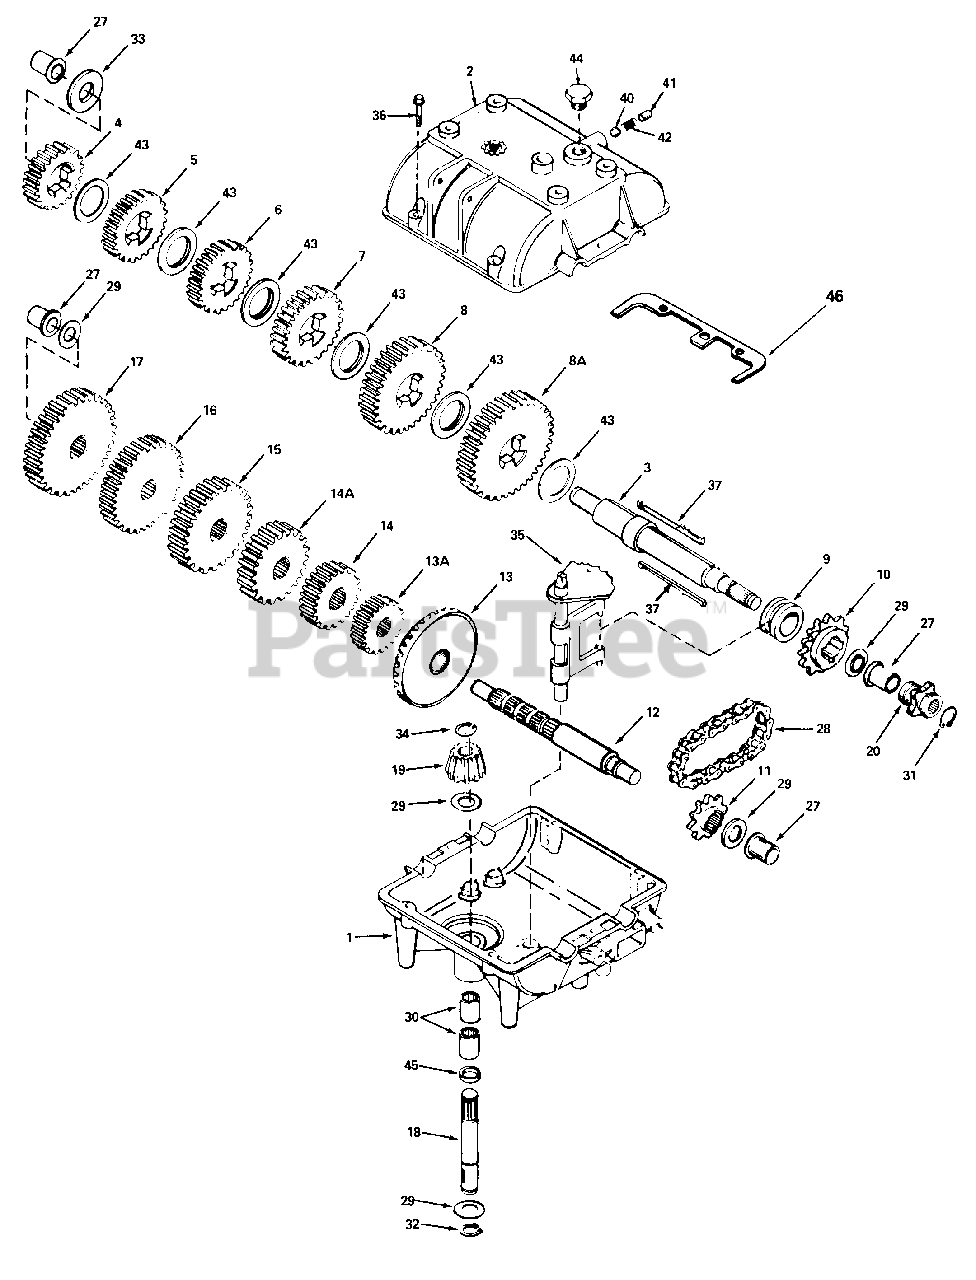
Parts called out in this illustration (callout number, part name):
1	Case, Transmission
2	Cover, Transmission
3	Shaft, Output
4	Gear, Spur (19 Teeth)
5	Gear, Spur (22 Teeth)
6	Gear, Spur (25 Teeth)
7	Gear, Spur (30 Teeth)
8	Gear, Spur (35 Teeth)
8A	Gear, Spur (37 Teeth)
9	Collar, Shift
10	Sprocket (14 Teeth)
11	Sprocket (10 Teeth)
12	Shaft, Counter
13	Gear, Bevel (42 Teeth)
13A	Gear, Spur (12 Teeth)
14	Gear, Spur (15 Teeth)
14A	Gear, Spur (20 Teeth)
15	Gear, Spur (25 Teeth)
16	Gear, Spur (28 Teeth)
17	Gear, Spur (31 Teeth)
18	Shaft, Input
19	Bevel Pinion, Input
20	Sprocket (7 Teeth)
27	Bushing, Flanged
28	Chain, Roller (No. 41 Chain, 22 Links)
29	Washer, Thrust
30	Bearing, Needle
31	Ring, Retaining
32	Ring, Retaining
33	Washer, Thrust
34	Ring, Retaining
35	Rod and Fork Ass'y., Shift
36	Screw, Flanged Hex Hd. Thd. Forming, 1/4-20 x 1-1/4
40	Ball, Steel, 5/16
41	Screw, Set, 3/8-16 x 3/8
42	Spring
43	Wash, Thrust
44	Plug
45	"O"-Ring
46	Gasket
